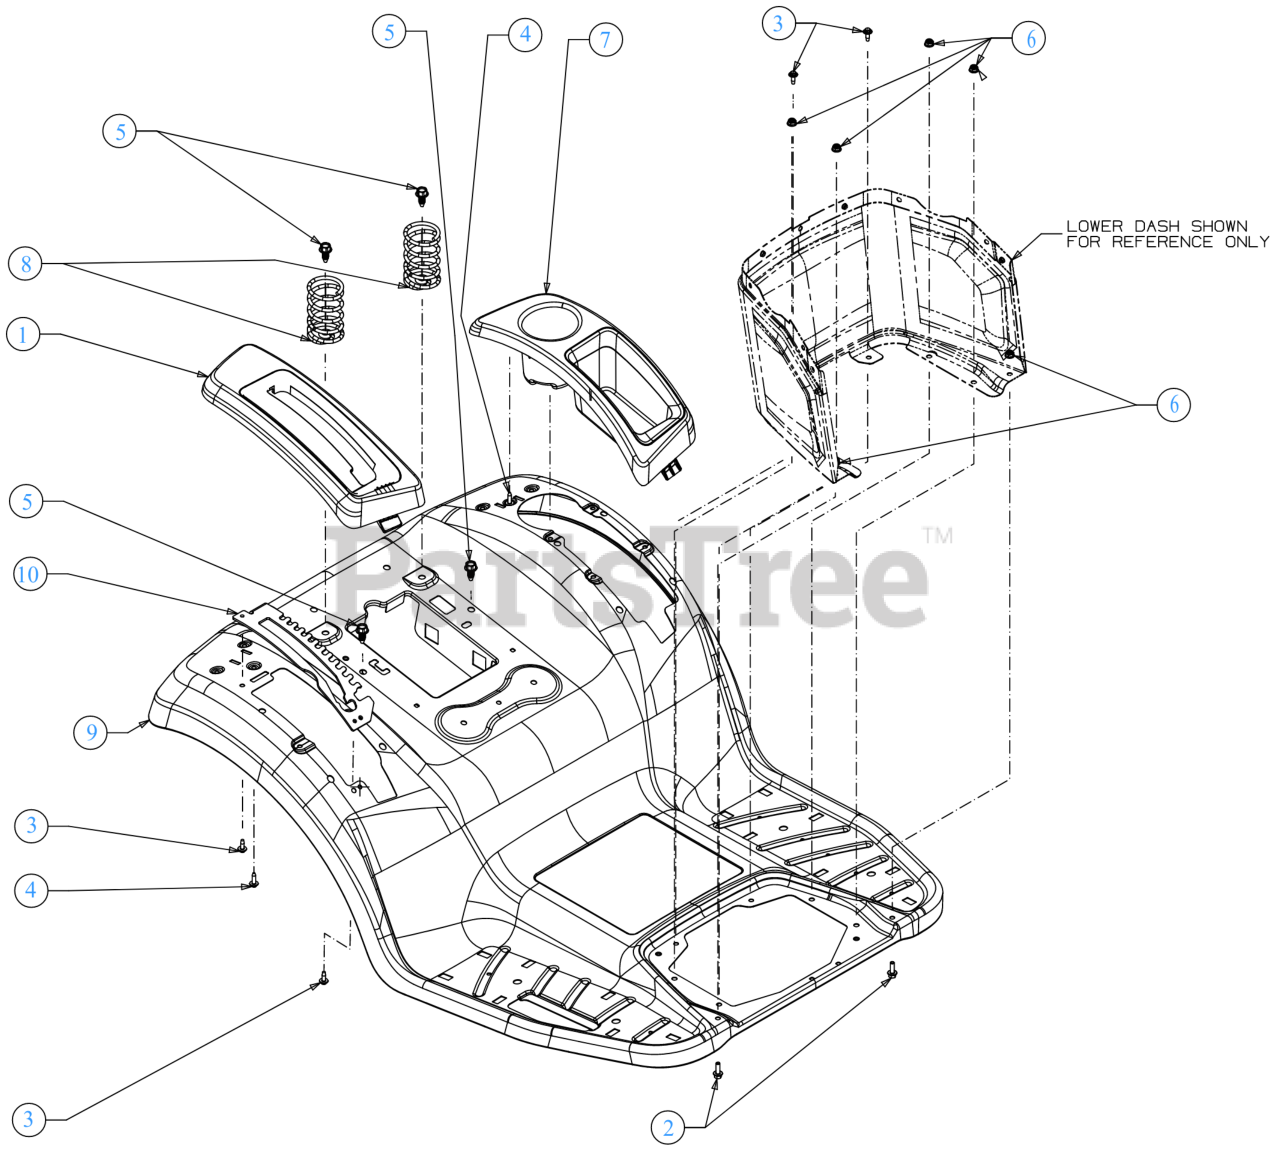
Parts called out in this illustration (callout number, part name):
1	FENDER COVER (RH)
2	SCREW 1/4-20 x .75 GR5
3	SCREW M6-1 x .625
4	SCREW 1/4-10 x .750
5	HEX SCREW WASH TT 3/8-16 x .875
6	FLANGE LOCK NUT
7	FENDER COVER (LH)
8	COMPRESSION SPRING 2.18 x 3.65 x .207
